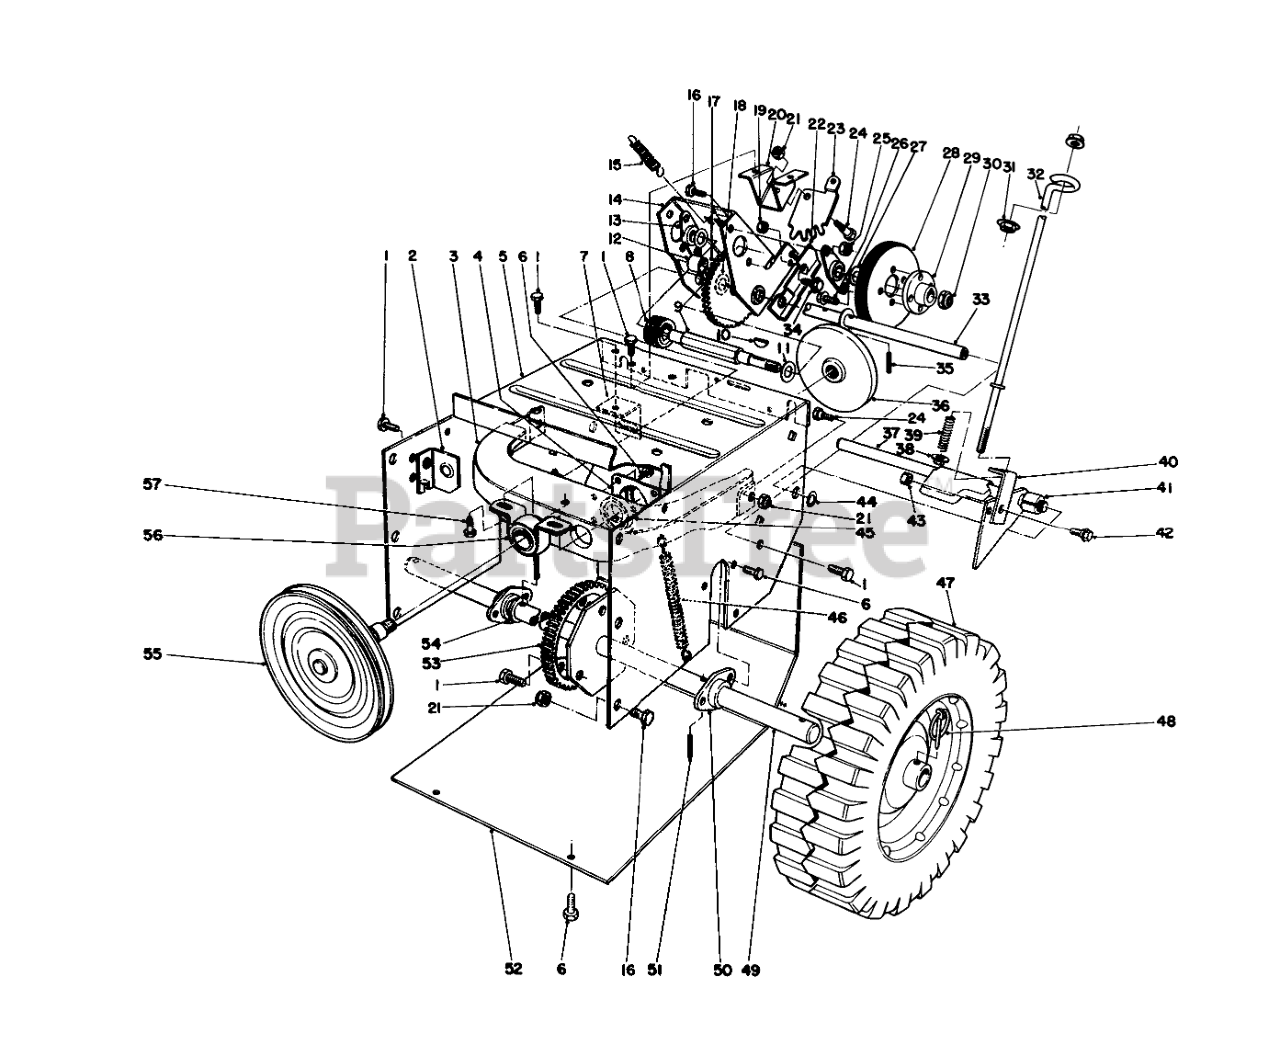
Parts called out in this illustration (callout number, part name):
1	SCREW-HWHTF
2	AUGER CLUTCH MTG FRT
3	"OBS" FRICTION PLT FRAME
4	CUP-BEARING
5	Frame-Traction
6	Bolt 1/4-20
7	BRACKET-MOUNT, REAR
8	PINION
9	SHAFT-WHEEL, FRICTION
10	KEY-WOODRUFF
11	WASHER-FLAT
12	5/8ID X 1LG BUSHING
13	BEARING-WHEEL, FRICTION
14	BRACKET-SLIDING
15	SPRING-TRACTION
16	SCREW-HH
17	Intermediate Gear & Bushing (Incl. Ref. #12)
18	WASHER-SPECIAL
19	NUT-LOCK, NI
20	MOUNT-LEVER
21	NUT-LOCK, NI
22	CAM-RECEIVER
23	GEAR-QUADRANT
24	BOLT-SHOULDER
25	NUT-LOCK, CONE
26	SCREW-HWHTF
27	WASHER-THRUST
28	WHEEL-FRICTION
29	HUB-WHEEL, FRICTION
30	NUT-LOCK, NI
31	NUT-HF
32	ROD-TRACTION, LOWER
33	SHAFT-PIVOT
34	Screw
35	PIN-SPRING
36	PLATE-FRICTION
37	Traction Engagement Asm.
38	NUT-HHF
39	SPRING
40	BRACKET-TRACTION
41	SPACER
42	SCREW
43	NUT-LOCK, NI
44	RING-RETAINING
45	BEARING-BALL
46	SPRING-PLATE, FRICTION
47	Wheel
48	PIN-LYNCH
49	AXLE SHAFT WA
50	BEARING-AXLE
51	PIN-SPRING
52	Bottom Cover
53	GEAR-AXLE
54	WASHER-THRUST
55	Pulley & Shaft
56	BUSHING ASM
57	SCREW-HWHTF
